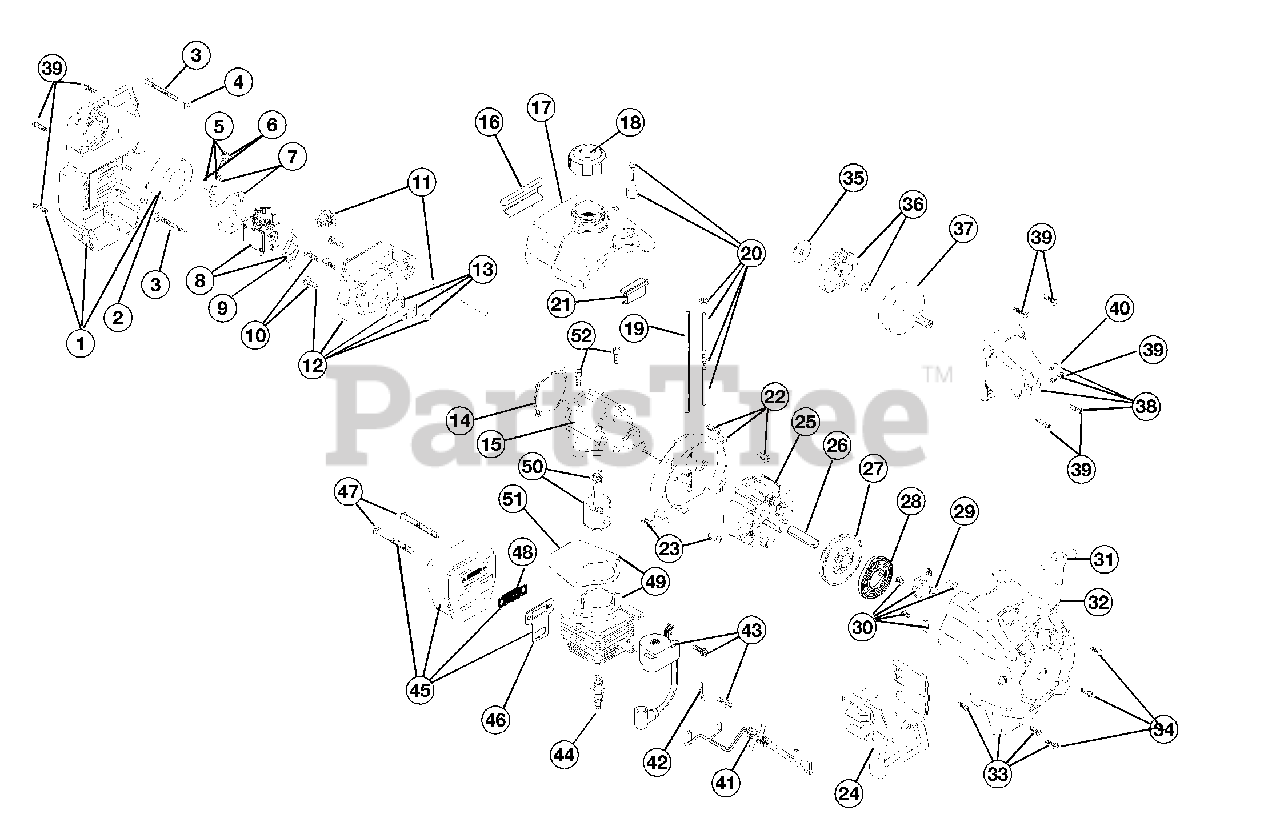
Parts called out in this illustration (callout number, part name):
1	Air Cleaner/Muffler Cover Assembly (includes 2 & 40)
2	Air Cleaner Filter
3	Carburetor Mounting Screw Assembly
4	Wavey Washer
5	Choke Lever Assembly (includes 6)
6	Choke Knob and Screw
7	Choke Lever and Plate (includes 5)
8	Carburetor Assembly (includes 9 & 20)
9	Carburetor Gasket
10	Carb Mount Screw
11	Primer and Hose Assembly
12	Carb Mount Assembly (includes 10 & 13)
13	Reed Assembly
14	Carburetor Mount Gasket
15	Crank Case Service Assembly (includes 10 & 23)
16	Rear Mounting Pad
17	Fuel Tank Assembly (includes 18-20)
18	Fuel Cap Assembly
19	Fuel Return Line
20	Fuel Line Assembly
21	Front Mounting Pad
22	Shroud Assembly
23	Shroud Screw
24	Shroud Extension and Stand
25	Flywheel Assembly
27	Recoil Pulley Assembly
28	Recoil Spring
29	Rope Guide
30	Pulley Retainer Assembly
31	Pull Handle
33	Starter Housing Assembly (includes 27-32 & 34)
34	Housing Screw
35	Clutch Washer
36	Clutch Rotor Assembly (includes 35)
37	Clutch Drum Assembly
38	Clutch Cover Assembly
40	Anti-Rotation Screw
41	Wire Leads and Sleeve
42	Ground Tab
43	Module Assembly
44	Spark Plug
45	Muffler Assembly (includes 46-48)
46	Exhaust Gasket
47	Muffler Mounting Bolt Assembly
48	Spark Arrestor Screen
49	Cylinder Assembly (includes 51 & 52)
50	Piston and Rod Assembly
51	Cylinder Gasket
52	Cylinder Bolt
